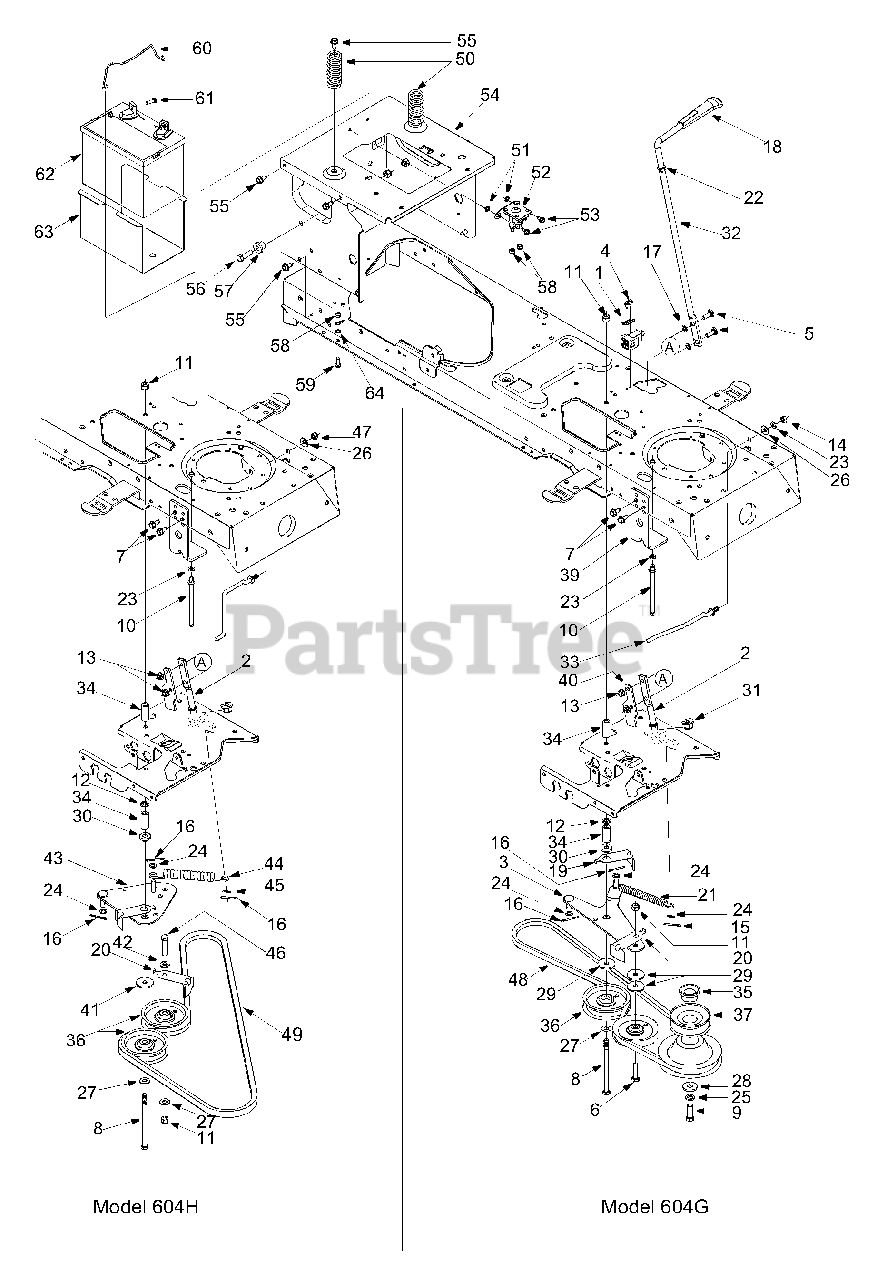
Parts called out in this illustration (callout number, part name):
1	Switch Plate
2	Lever Assembly: PTO Engage
5	Carriage Screw: Special
6	Hex Bolt 3/8-16 x 1.5
7	AB Screw 5/16-12 0.75
8	Hex Bolt 3/8-16 x 5.5
9	Hex Bolt 7/16-20 x 1.25
10	Belt Guard Pin
11	Lock Nut
12	Push Nut
13	Flange Lock Nut
14	Hex Nut 5/16-18
15	Cotter Pin
16	Cotter Pin
17	Speed Nut
18	PTO Knob
19	Belt Guard
20	Belt Guard
21	Extension Spring
22	Flat Washer
23	Lock Washer
24	Flat Washer
25	Lock Washer
26	Bell Washer
27	Flat Washer
28	Flat Washer
29	Flat Washer
30	Spacer
31	Hex Split Flange Bearing
32	Handle: Deck Engage
33	Rod: Belt Keeper
34	Spacer
35	Spacer
36	Idler Pulley
37	Engine Pulley, 3.56 OD x 5.56 Dia., 42" deck
37	Engine Pulley, 3.39 x 6.12 Dia., 46" deck
38	Idler Pulley
41	Flat Washer
42	Flat Washer
44	Extension Spring
45	Flat Washer
46	Hex Bolt 3/8-16 x 1.75
47	Hex Lock Nut 5/16-18
48	V Belt 42" Deck
49	V Belt 46" Deck
50	Compression Spring
51	Lock Washer
52	Solenoid
53	TT Screw 1/4-20 x 0.5
56	Hex Bolt 3/8-16 x 1.25
57	Shoulder Spacer
58	Lock Nut 1/4-20
59	TT Screw 1/4-20 x 0.75
60	Battery Hold-Down Rod
61	Carriage Screw
62	Battery
